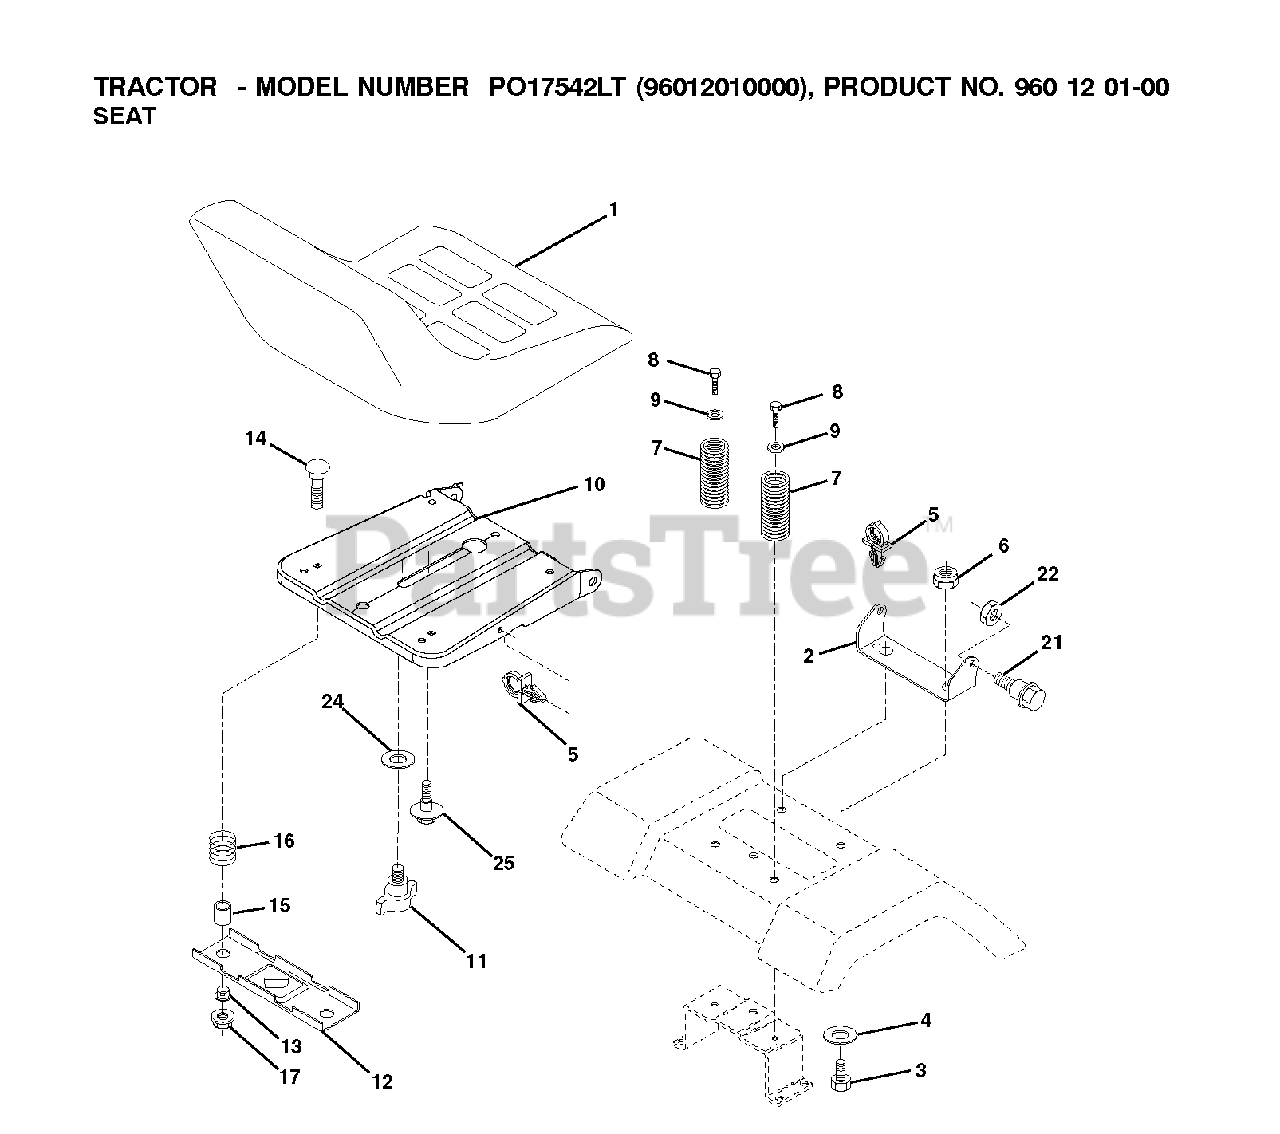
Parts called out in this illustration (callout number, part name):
1	SEAT.XG090.BLK.KB/BLT.NO-LOG
2	SEAT PIVOT BRKT
3	BOLT, HEX 3/8-16X1
4	WASHER PM
5	PUSH CLIP
6	NUT
7	SPRING COMPRESSION
8	SCREW 3/8-16X1
10	PAN.ASM.SEAT.1SLOT
11	KNOB.SEAT.ADJ.WINGNUT
12	BRKT.MNTNG.SWITCH.SEAT.BLACK
14	BOLT.ROUND.HEAD.SQUARE.NECK
15	SPACER SPLIT 28X.96
17	NUT T
21	BOLT.SHOULDER.5/16-18
22	NUT.71038.31-18.HEX.NYLOCK
25	BOLT,SHOULD
